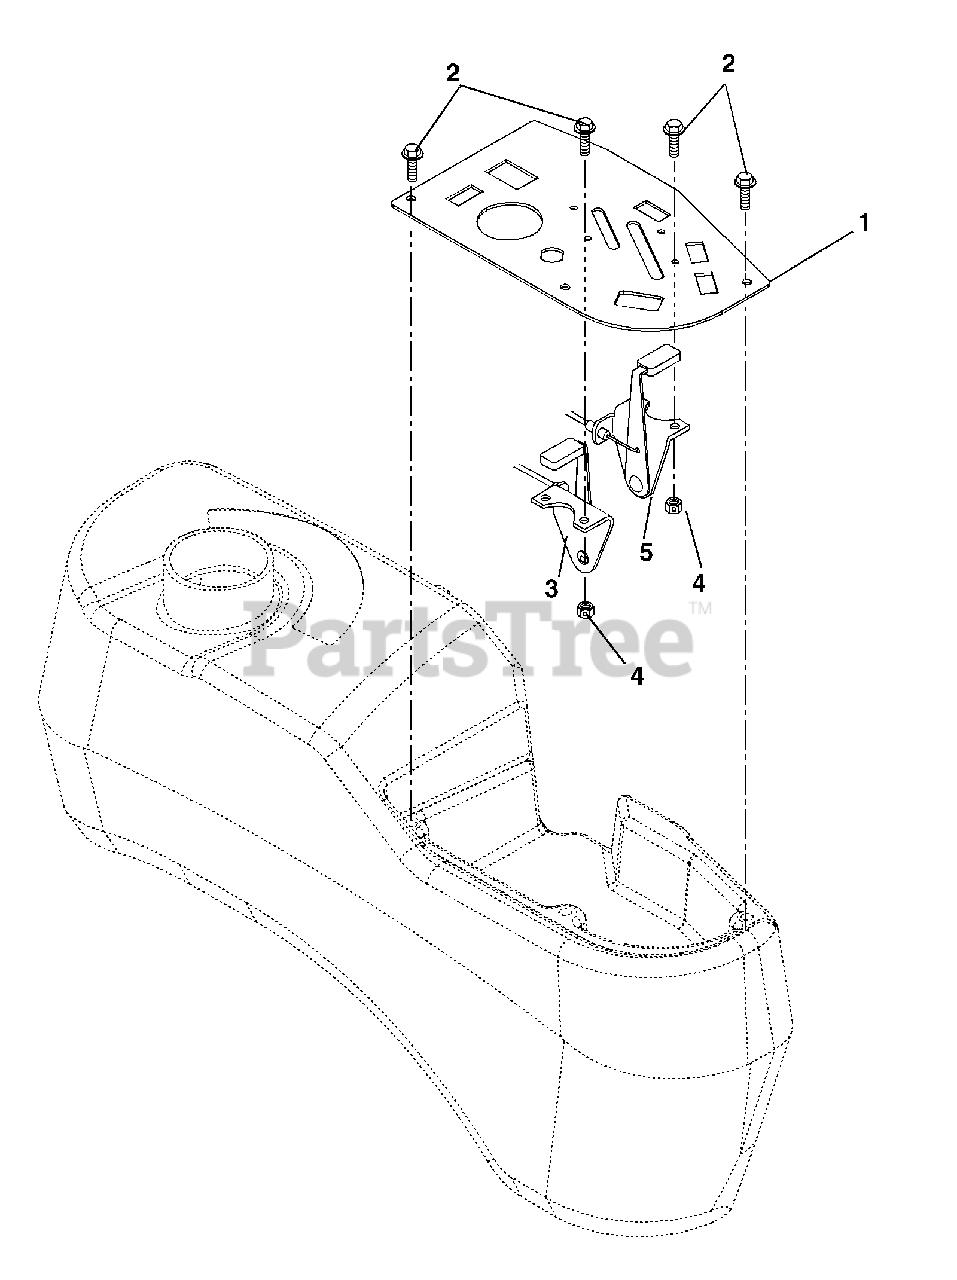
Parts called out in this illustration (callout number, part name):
1	Panel-Control
2	Screw-Machine 10-24 x .50 Hex Washer Head(060, 061, 318, 319)
2	Screw-Machine 10-24 x .50 Hex Washer Head (058, 059)
3	Throttle, Control (060, 061, 318, 319)
3	Throttle, Control (058, 059)
4	Nut-Locking-Nylon 10-24 With Insert(060, 061, 318, 319)
4	Nut-Locking-Nylon 10-24 With Insert (058, 059)
5	Choke Control (058, 059)
